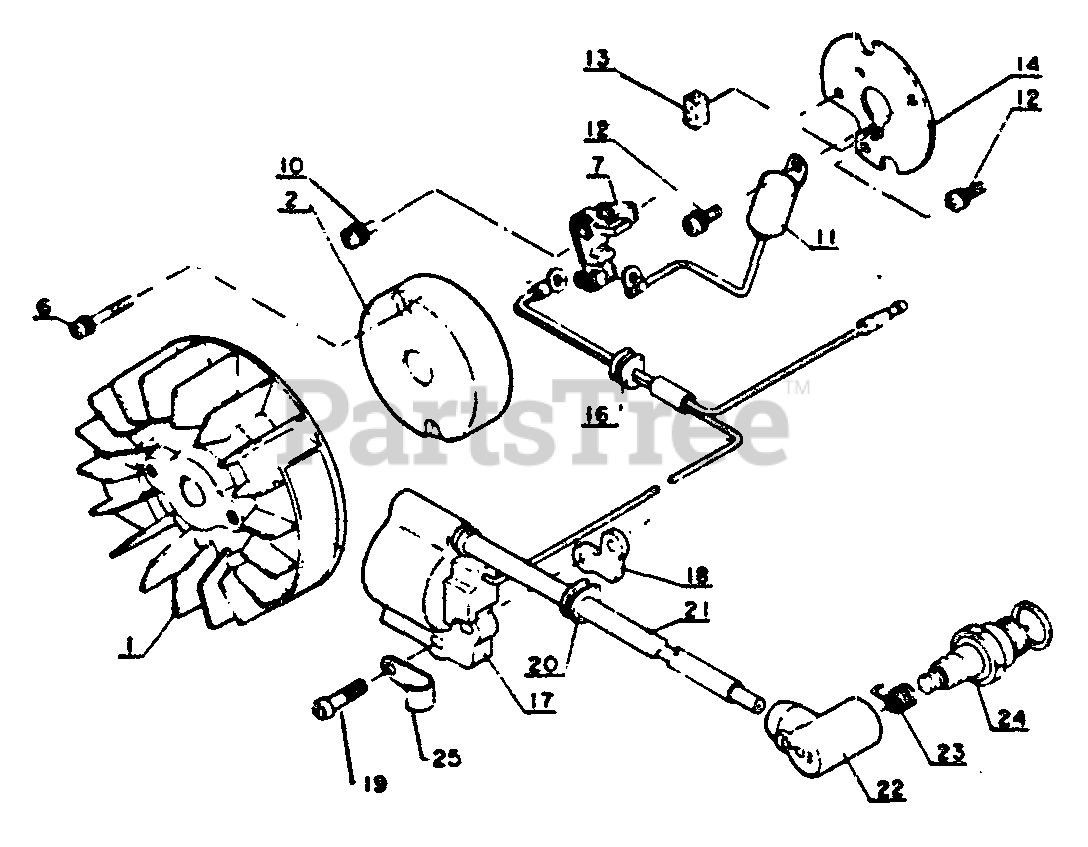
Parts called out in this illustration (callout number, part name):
1	FLYWHEEL
2	COVER, BREAKER
6	SCREW - 3X22
7	CONTACT POINT SET
10	SCREW - 4X8
11	CONDENSER
12	SCREW - 4X12
13	PAD
14	PLATE, STATOR
17	COIL, IGNITION
19	SCREW - 4X20
20	BUSHING
22	CAP, SPARK PLUG
23	TERMINAL, SPARK PLUG CAP
24	SPARK PLUG -- BM-6A
25	CLIP
